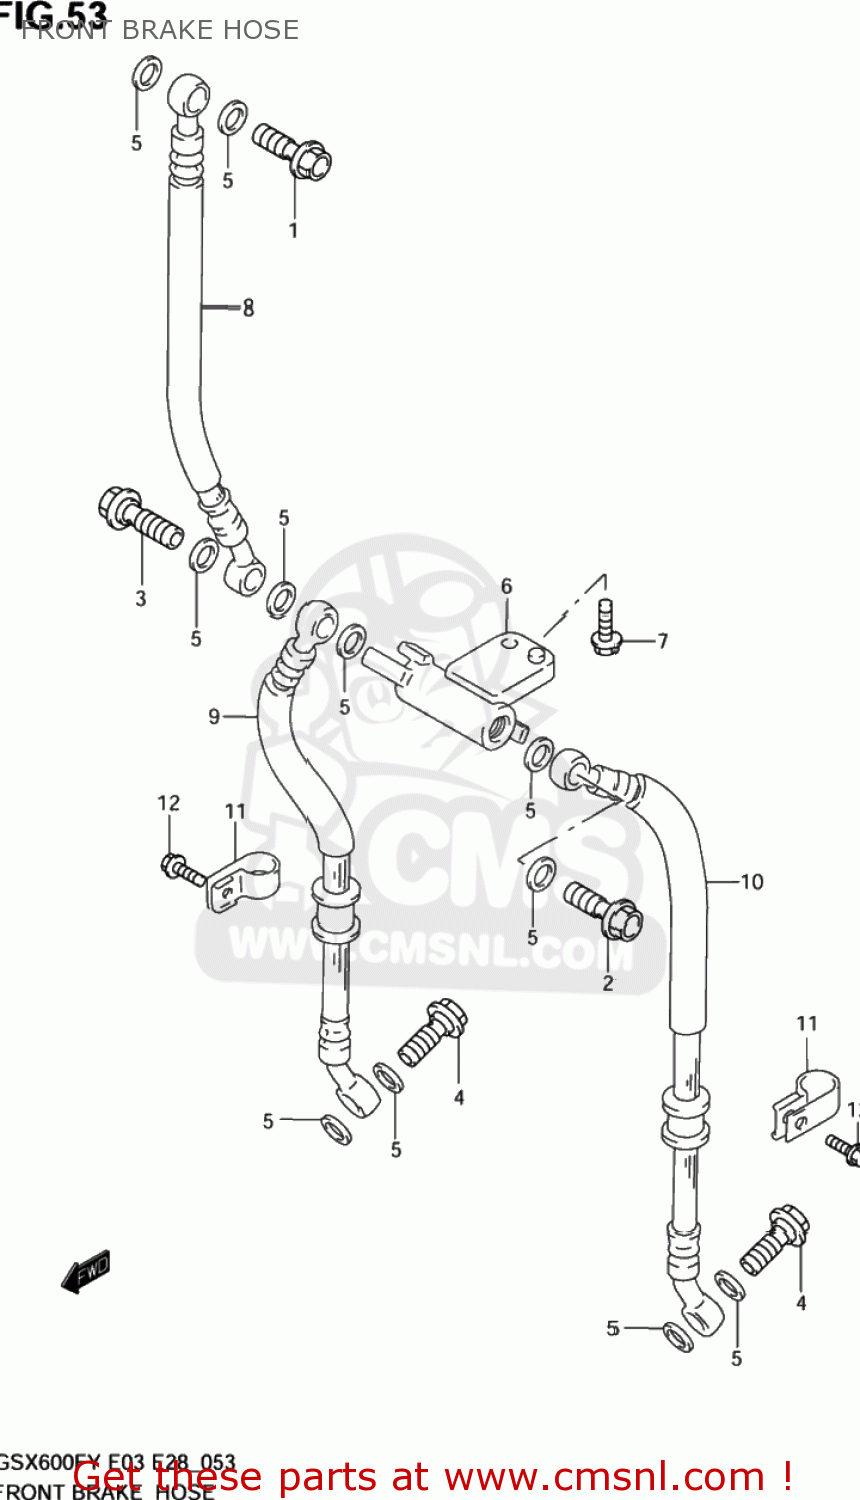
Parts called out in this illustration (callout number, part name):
1	BOLT UNION
2	BOLT UNION
3	BOLT UNION
4	BOLT UNION
5	WASHER(10X15X1.5)
6	JOINT,BRAKE HOSE
7	BOLT
8	HOSE COMP,FRONT BRAKE NO
9	HOSE COMP,FRONT BRAKE
10	HOSE COMP,FRONT BRAKE
11	CLAMP,FR BRAKE HOSE NO.2
12	BOLT
